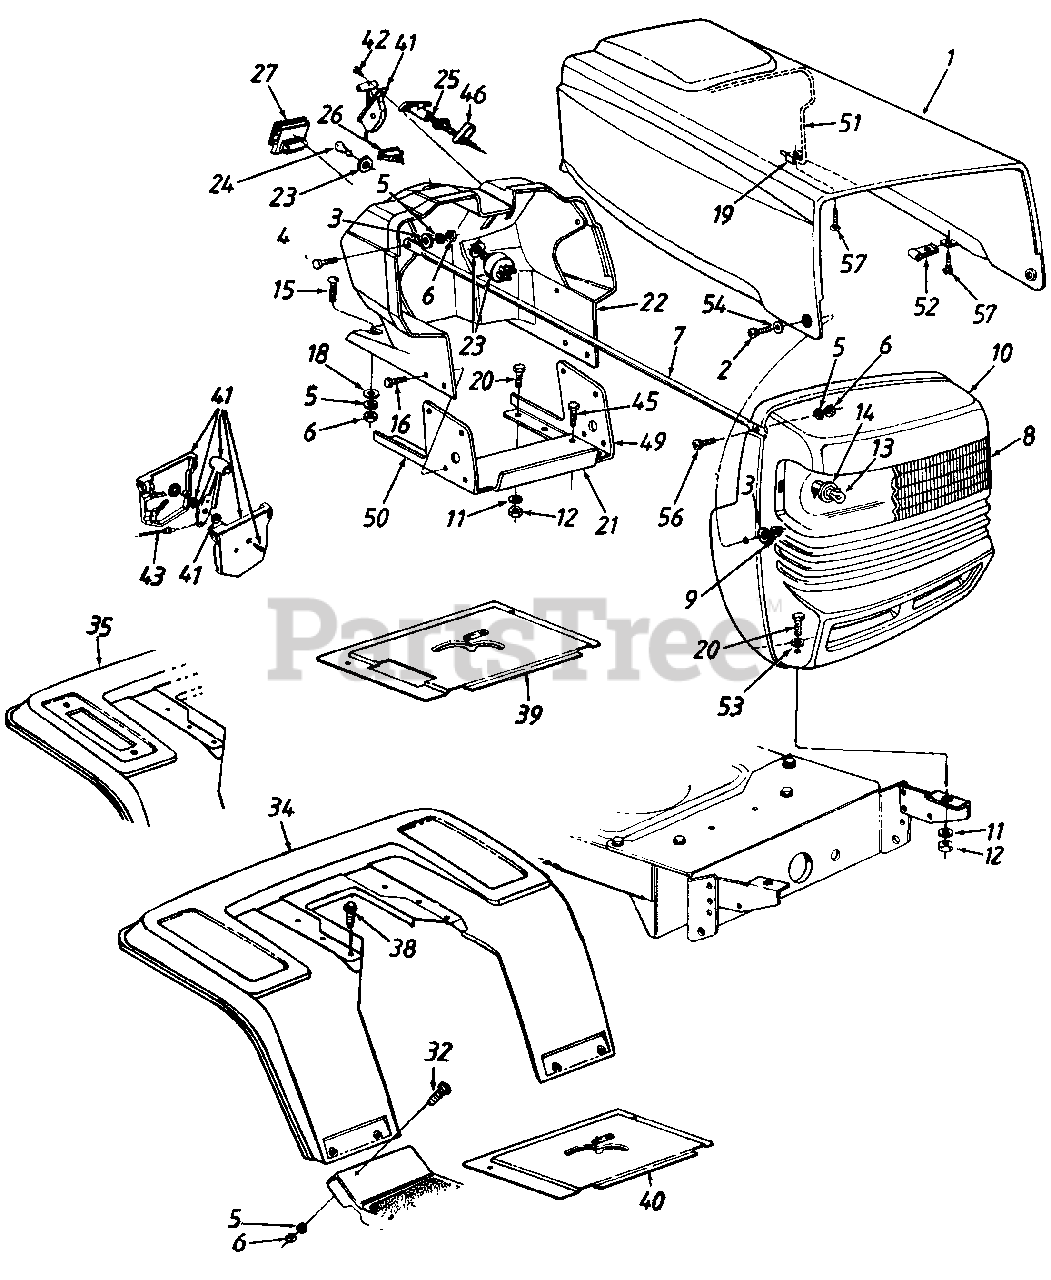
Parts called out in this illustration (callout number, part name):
3	Fl-Wash .28" I.D. x .75" O.D.
4	Hex Bolt 1/4-20 x .88" Lg.
5	L-Wash. 1/4" I.D.
6	Hex Nut 1/4-20 Thd.
9	Flange L-Nut 1/4-28 Thd.
12	Hex Nut 5/16-18 Thd."
13	Lamp
14	Socket
15	Carriage Bolt 1/4-20 x .75" Lg.
16	Hex Wash. Hd. TT-Tap Scr. 1/4-20 x .5" Lg.
18	Bolt Retainer 1/4" I.D.
19	Speed Nut #10-24 Thd.
20	Hex Bolt 5/16-18 x .75" Lg.
23	Ignition Switch
24	Ignition Key
25	Choke Control
26	Light Switch
27	Ammeter
32	Truss Mach. Scr. 1/4-20 x .5" Lg.
41	Throttle Box Ass'y.
42	Truss Mach. AB-Tap Scr. #10 x .5" Lg.
43	Throttle Control Wire
45	Hex Wash. Hd. B-Tap Ser. 5/16-18 x .5" Lg.
46	Choke Retainer
52	Flat Fastener (Special)
53	Fl-Wash .344" I.D. x 1" O.D.
54	Spr. Wash .39" I.D. x .62" O.D.
56	Pan Hd. Scr. 1/4-20 x .75" Lg.
57	Truss Mach. Scr. #10-24 x .5" Lg.
